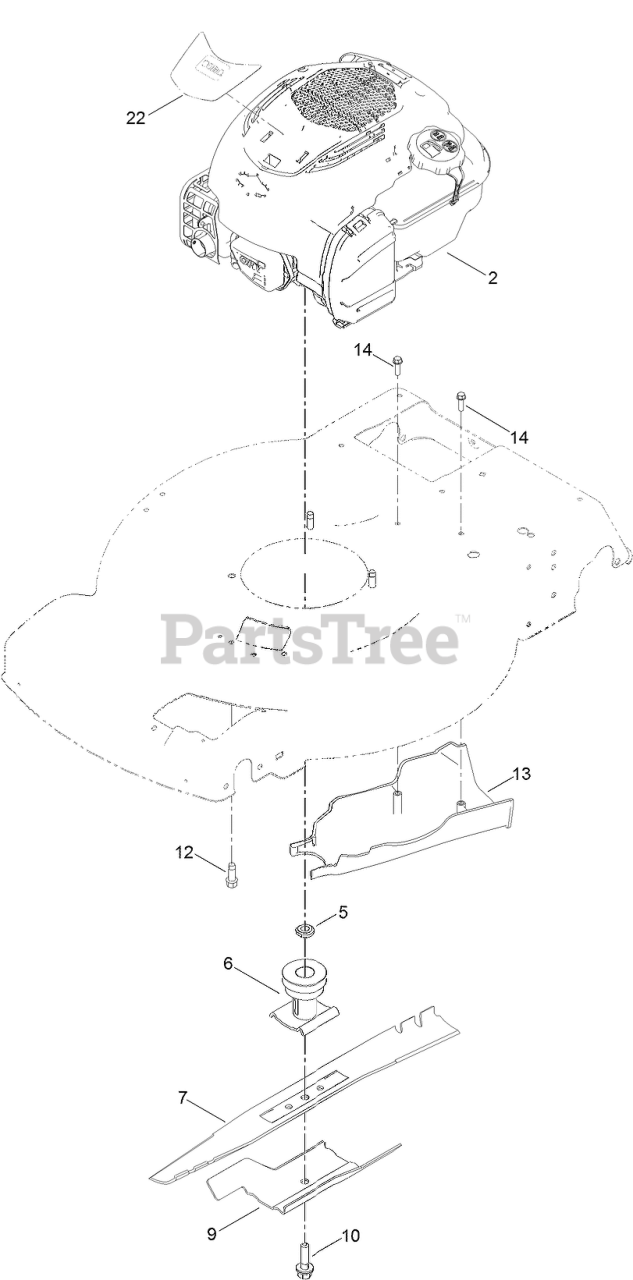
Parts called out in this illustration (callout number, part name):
5	SPACER-DRIVER
6	DRIVER-BLADE
9	ACCELERATOR-BLADE
10	BOLT-BLADE
12	SCREW-TAPTITE
13	COVER-BELT, REAR
14	SCREW-PLASTITE, HWH
22	DECAL-SHROUD
